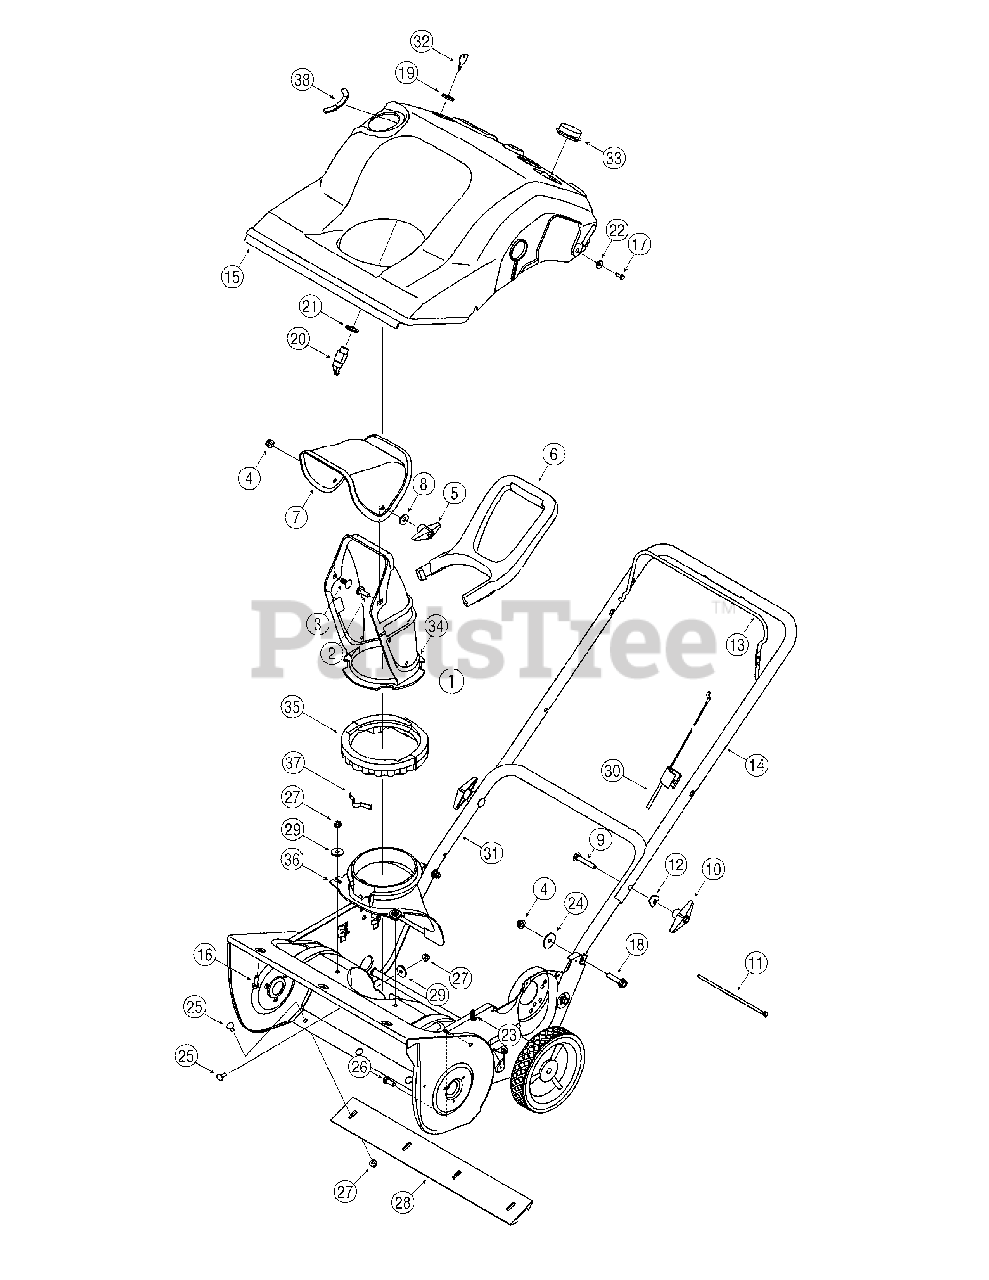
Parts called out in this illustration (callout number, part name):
1	Chute Assembly
2	Carriage Bolt 5/16-18 x 1.0"
3	Carriage Bolt 5/16-18 x 0.750"
4	Flange Lock Nut, 5/16-18
5	Chute Knob Assembly
6	Chute Handle
7	Upper Chute
8	Washer
9	Carriage Bolt 5/16-18 x 2.0 Gr. 1
10	Handle Knob Assembly 5/16-18
11	Cable Tie
12	Saddle Washer .320 x .93
13	Bail, Gull Wing
15	Shroud Assembly 2 Cyc. 4.5hp.
16	Screw, 1/4-15 x .50
17	Self-tapping Screw, #10-16 x .625"
18	Hex Flange Screw 5/16-18 x 1.50 Gr. 5
19	Hex Nut 5/8-32 x .12 Special
20	Key Switch-Electric Start
21	Lock Washer Internal .625 x 1.058
22	Flat Washer .194" x .62" x .063
23	Extension Spring
24	Flat Washer .330 x 1.25 x .06
25	Screw, 1/4-20 x .62
26	Truss Machine Screw, 5/16-18 x .75
27	Hex Flange Lock Nut, 1/4-20
28	Shave Plate,19.88
29	Flat Washer .265 x .938 x .120
30	Control Cable
32	Ignition Key
33	Spark Plug Cover
34	Lower Chute 5" Dia
35	Ring-Lower Chute
36	Chute, Adapter 5" Dia
37	Chute Adjustment Spring
38	Strip Trim
